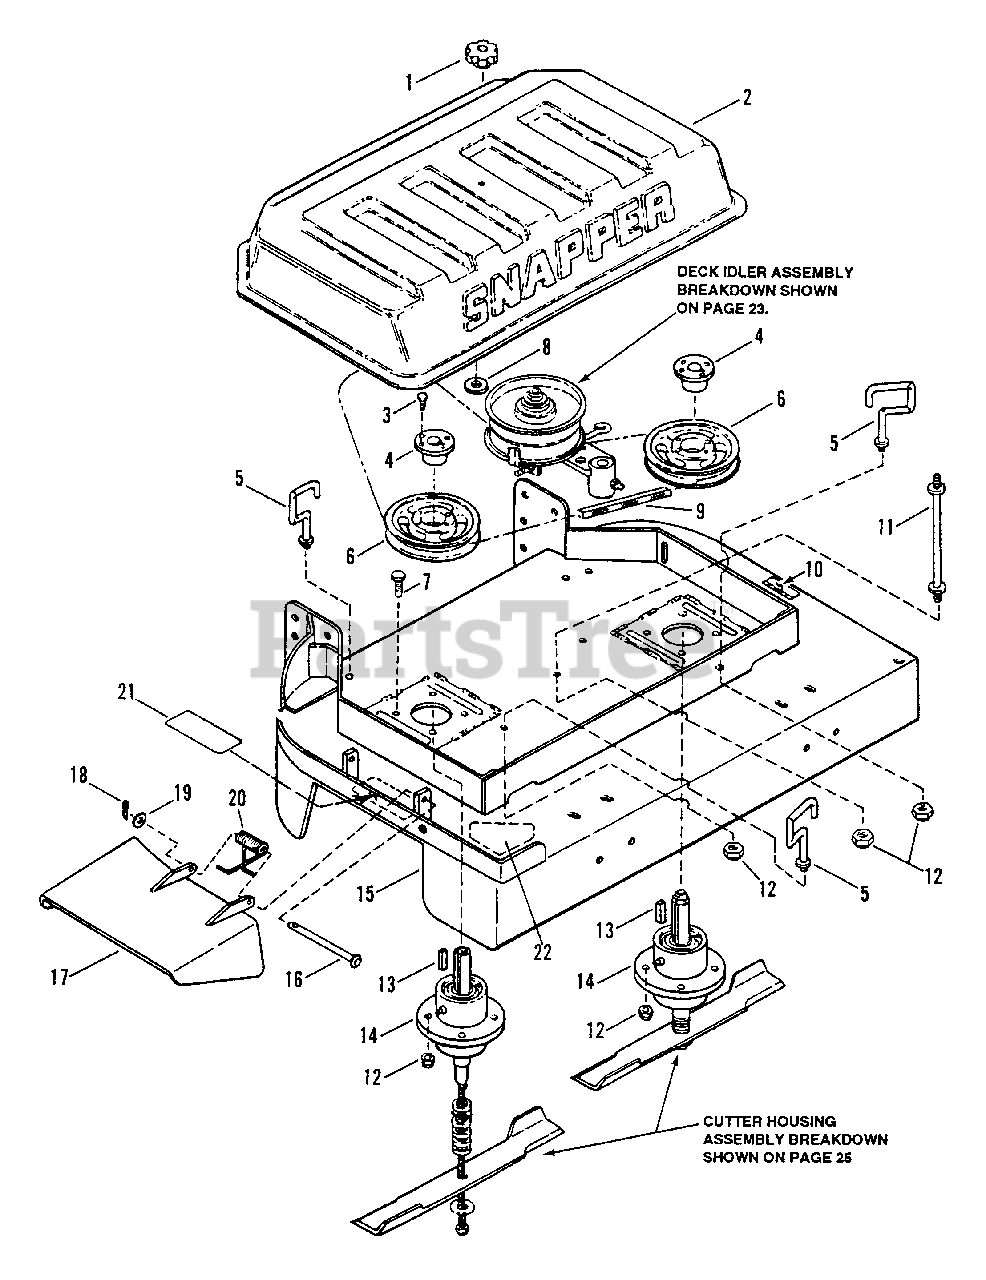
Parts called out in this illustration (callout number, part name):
1	KNOB, Hood
3	BOLT, 1/4-20 x 7/8" Hex Head Cap
4	BUSHING, Taperlock
6	PULLEY, Cutter Blade Drive
7	BOLT, 3/8-16 X 1-1/4" GD5 CZ
8	WASHER, 13/32" I.D. x 1-1/2" O.D.
9	BELT, 36" Deck, 83.625" E.L. HB
10	DECAL, Caution
11	STUD, Hood Mount
12	NUT, 3/8-16 HEX NYLON LOCK
13	KEY, Spindle, 1/4 x 1/4 x 2 1/2"
14	ASSEMBLY, Cutter Housing
15	WELDMENT, 36" Deck
16	ROD, Chute Pivot
17	DEFLECTOR, 36" Chute
18	PIN, 3/32 x 1" Cotter
19	WASHER, 5/16 Flat
20	SPRING, Chute
21	DECAL, Caution
22	DECAL, Danger
